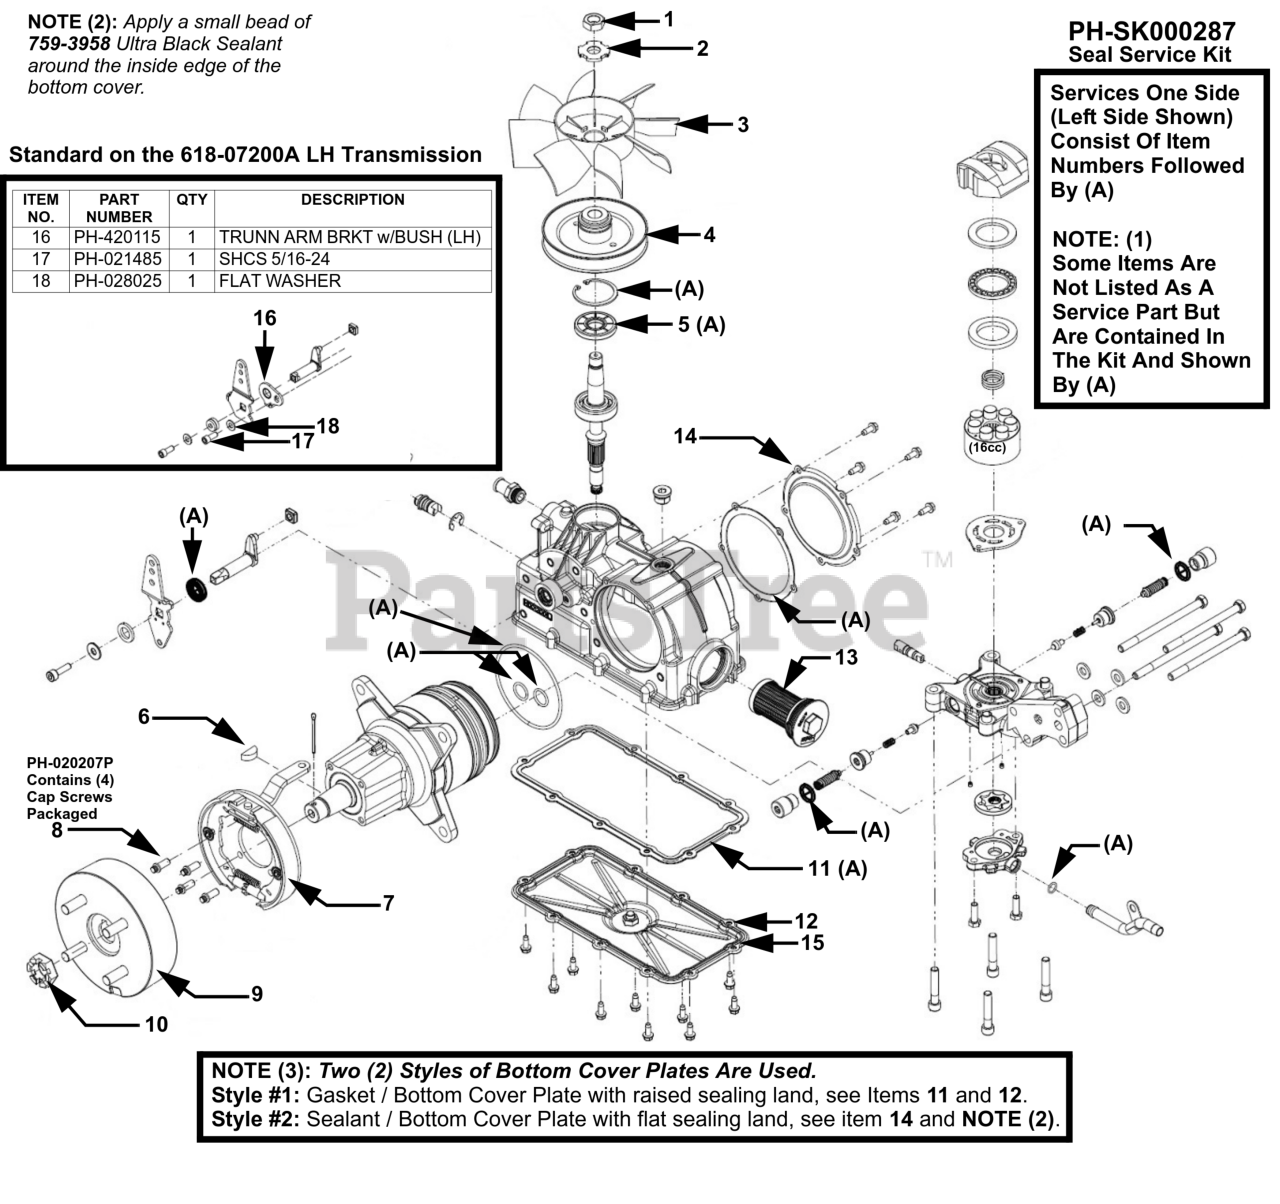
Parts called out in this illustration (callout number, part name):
6	WOODRUFF KEY
7	BRAKE ASSEMBLY-ON HOLE LEVER
8	SCREW-CAP (QTY 4)
9	DRUM-4 BOLT BRAKE
10	NUT-SLOTTED
11	BOTTOM COVER GASKET
12	BOTTOM COVER
14	SIDE COVER PLATE
15	BOTTOM COVER
16	TRUNNION ARM BRACKET (LH)
17	CAP SCREW 5/16-24
18	FLAT WASHER
19	BRACKET-ROTATING
A	SEAL SERVICE KIT
